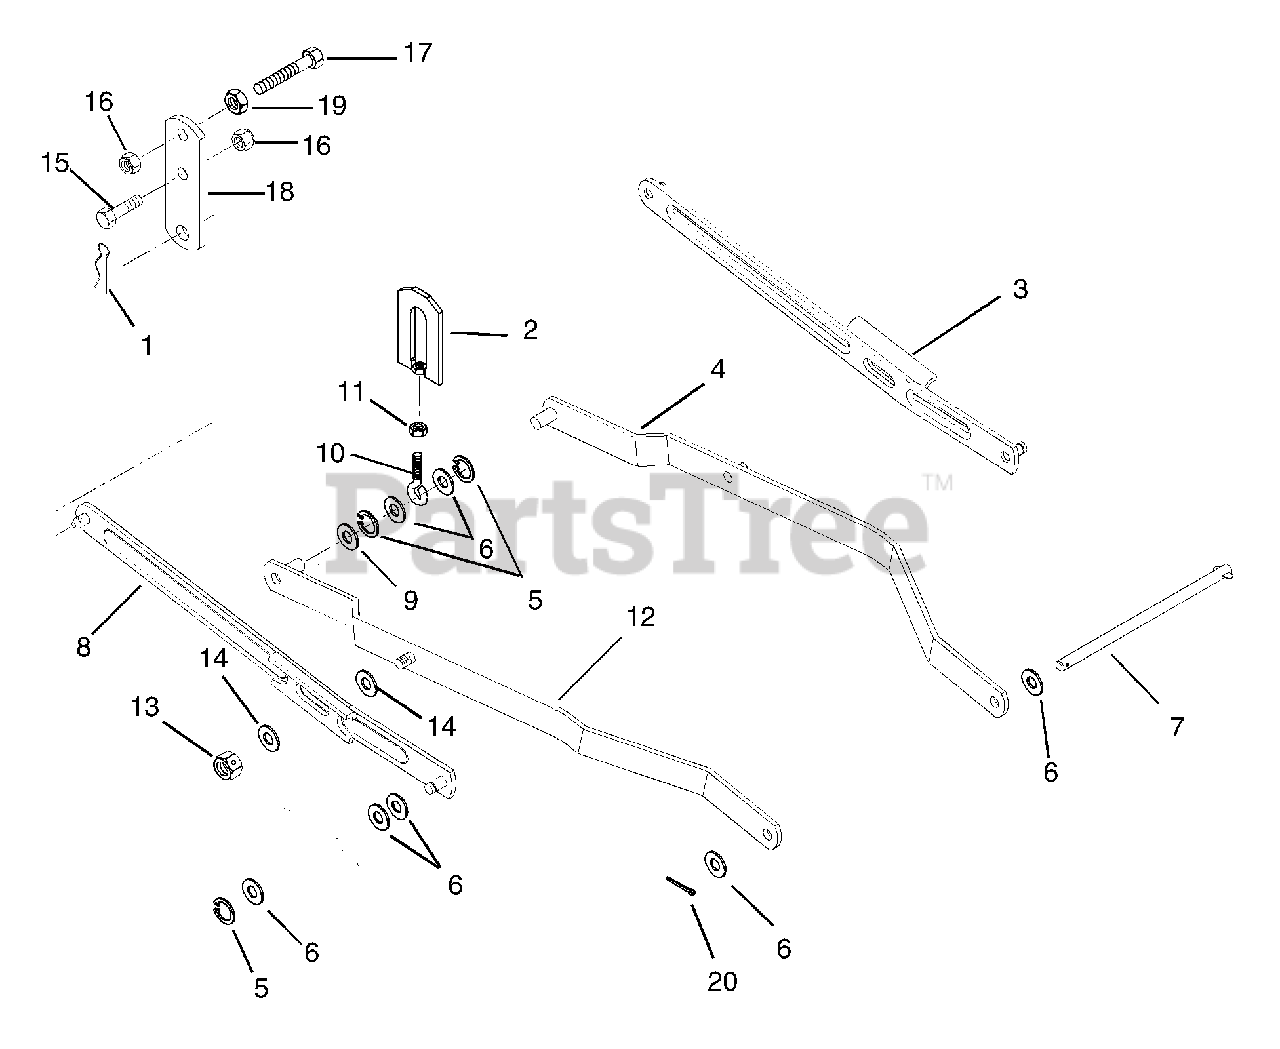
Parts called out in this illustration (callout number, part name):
1	PIN-HAIR-EXT .12X.31X2.37 YWZC
2	LINK, ADJUSTMENT
3	REAR HANGER, L.H.
4	L.H. LIFT ARM
5	RG-RTNG-EXT .500X.050 (SNAP)
6	@WSHR-FL-STL.531X1.06X.095YWZC
8	REAR HANGER, R.H.
9	@WSHR-FL-STL.531X1.06X.095YWZC
11	NUT-HEX-JAM .375-16 YWZC
12	R.H. LIFT ARM
13	@NUT-LK-CTR .62-11 YWZC
14	@WSHR-FL-STL.656X1.31X.095 YWZ
15	@BLT-HEX .38-16X.75 GR5 YWZC
16	@NUT-LK-CTR .38-16 YWZC
17	@BLT-HEX .38-16X1.75 GR5 YWZC
18	HANGER BRACKET
19	@NUT-HEX .38-16 YWZC
20	@PIN-CTR .12X1.00 EXTPRSQCT YZ
